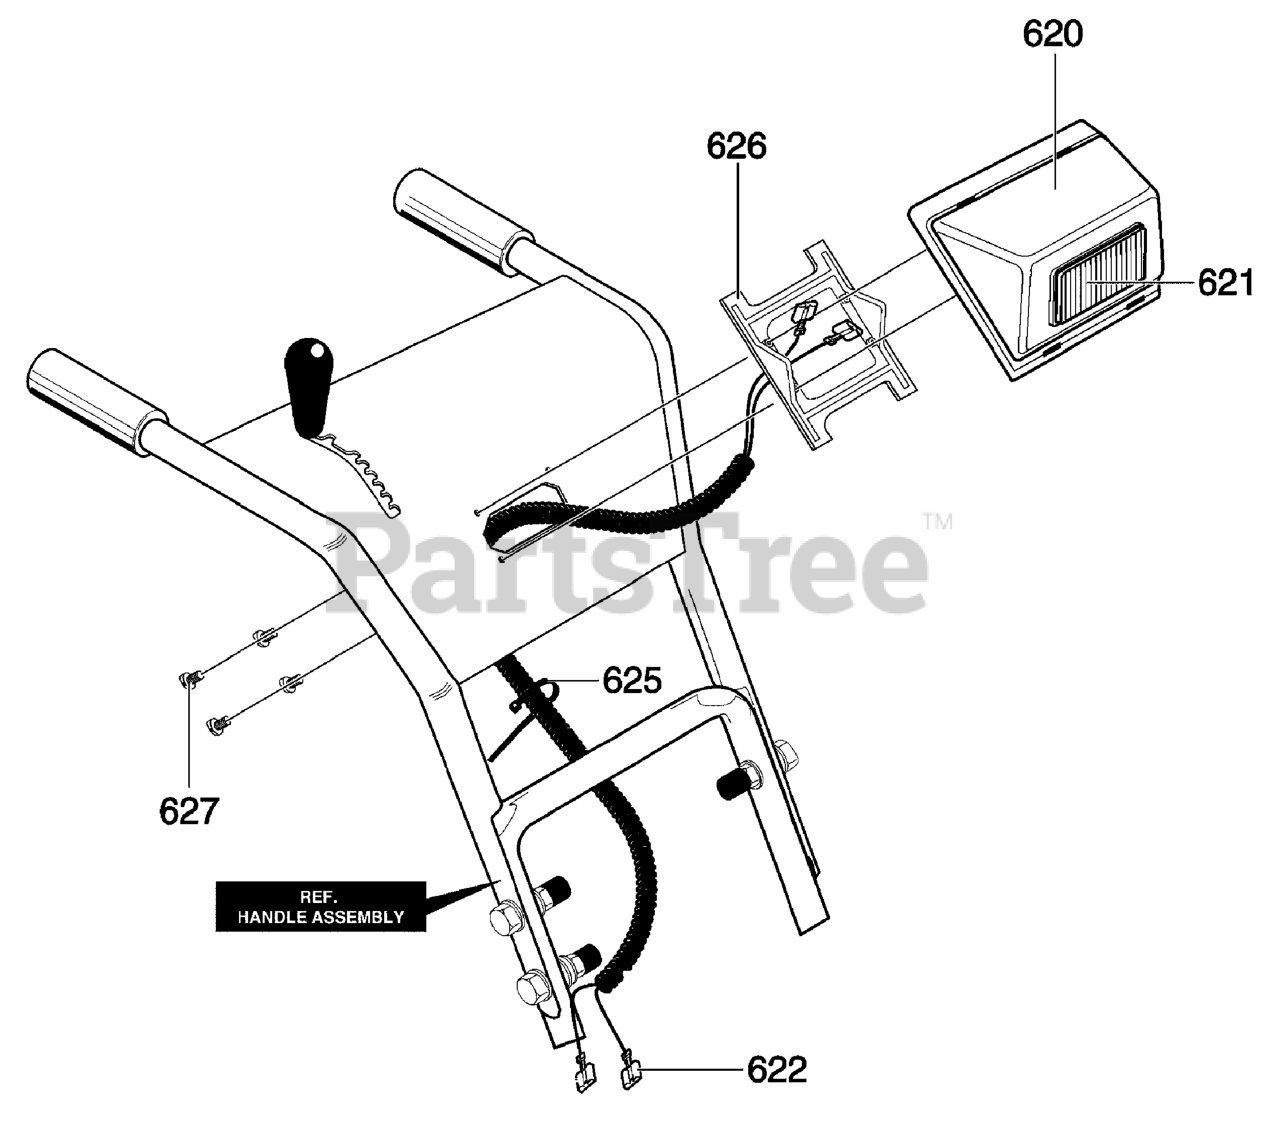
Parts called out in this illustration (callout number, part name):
620	CASE, HEADLIGHT
621	HEADLIGHT ASSEMBLY
622	WIRE, HARNESS
625	CABLE TIE
626	BRACKET, HEADLAMP
